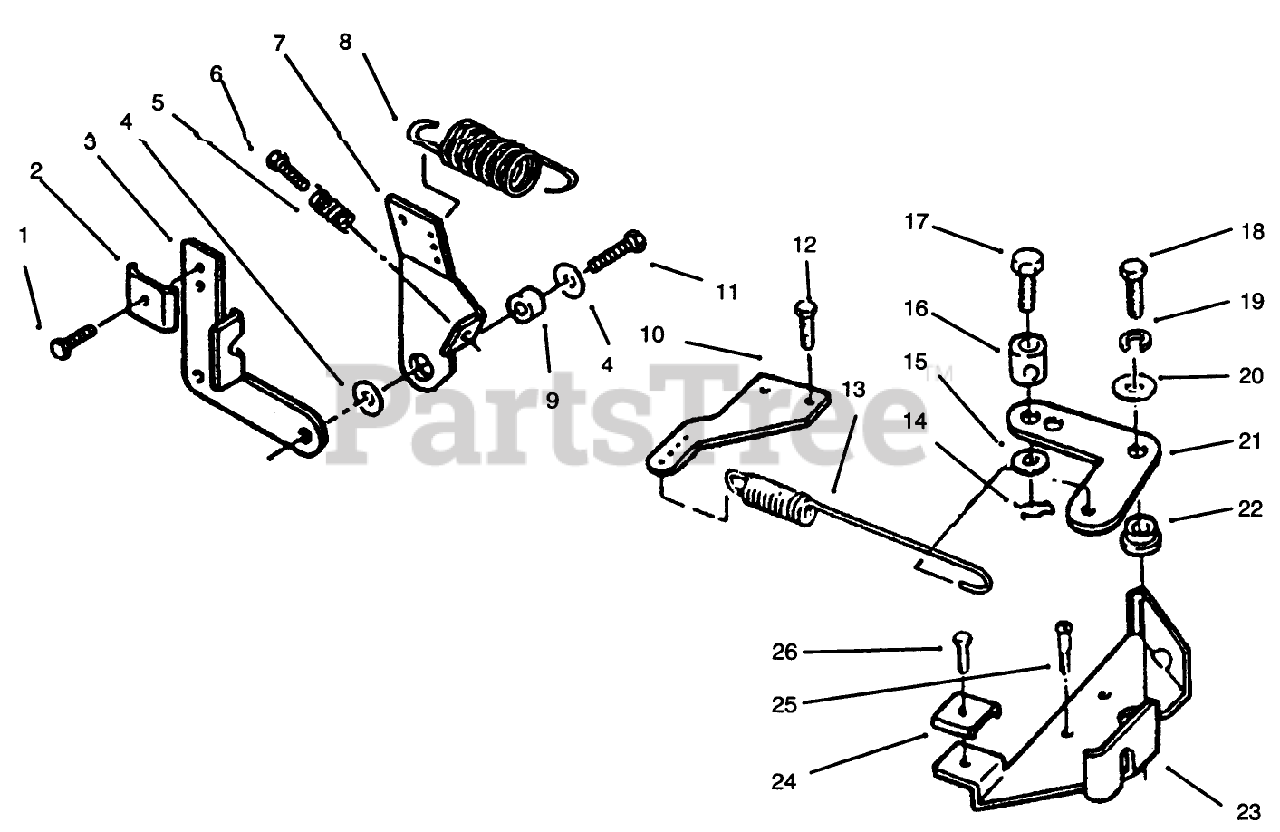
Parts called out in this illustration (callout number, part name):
1	SCREW-TAPPING
4	WASHER-FLAT
5	SCREW-TAP
6	SPRING
9	BUSHING
12	SCREW-TAPPING PAN HD
14	PIN-COTTER
16	BUSHING
17	SCREW
19	WASHER-LOCK, SPRING
20	WASHER-FLAT
23	BRKT-GOVERNOR CONTRL
25	SCREW-HWH
26	HEX HD CAP SCREW
